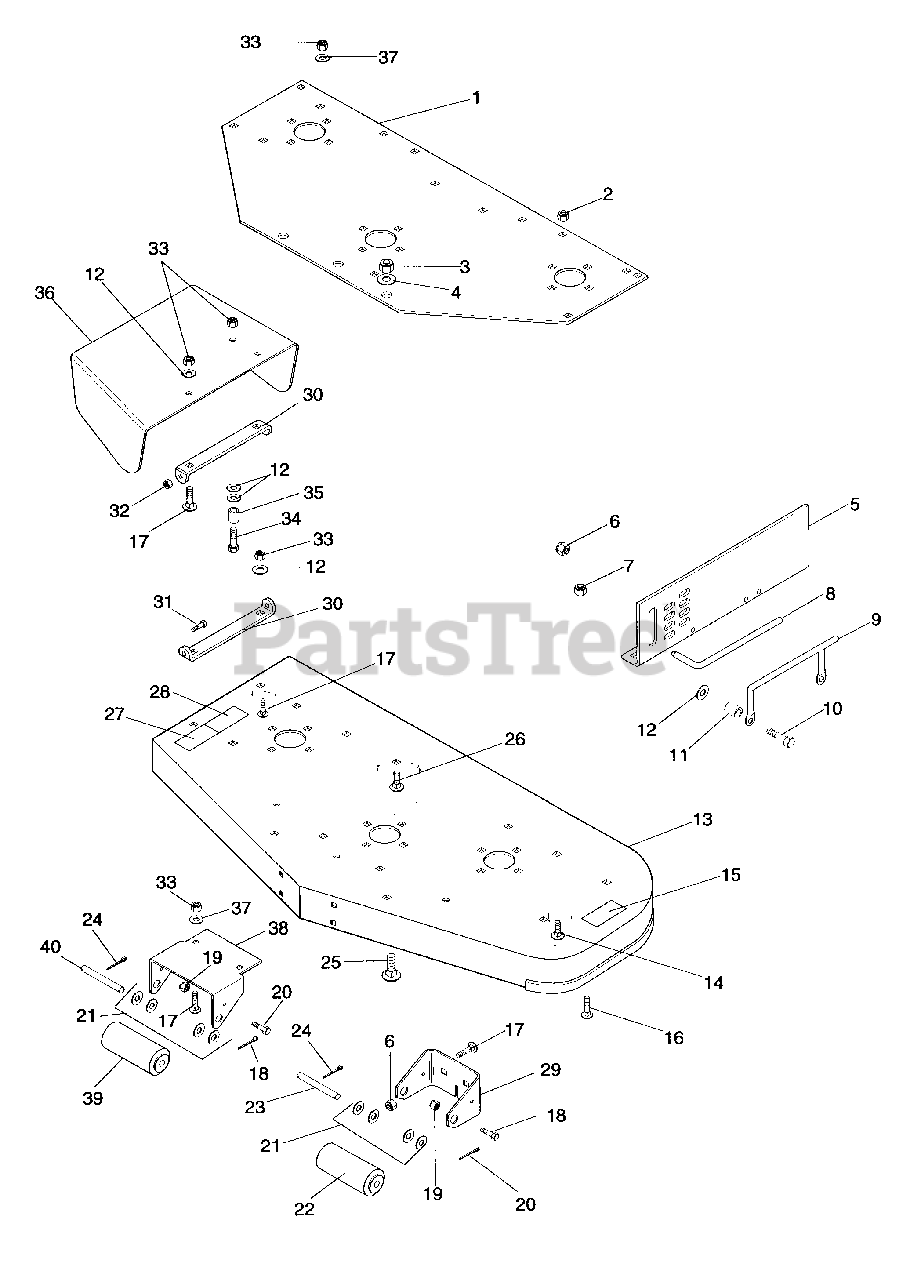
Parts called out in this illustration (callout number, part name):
1	Plt,Support
2	Nut - Lk - Nyl .312 - 18 Pl
3	Nut - Lk - Nyl .50 - 13 Pl
4	Wshr - FL - Stl .531 x 1.250 x .100
5	Brkt, Mwr Side Sprt L.N.
5	Brkt, Mwr Side Sprt R.H.
6	Nut - Lk - Nyl.375-16 PL
7	Nut - Lk - Nyl .312 - 18 PL
8	Pin, Mower Locking
9	Handle
10	Blt - Hex .38 - 16 x 1.75 Pl Gr 5
11	Bushing
12	Wshr - Fl - Stl .406 x .812 x .065 Pl
13	Wldmt, 50" Mwr Fabricated
14	Blt, 5/16 - 18 x .625 Rdhdsqnk
15	Decal, Danger Foot
16	Blt, Carriage 5/16 - 18 x 1.0
17	Blt - Rdhdsqnk .38 - 16 x 1.0 Pl
18	Blt - Hex .25-20 x.75 Pl Gr 5
19	Nut - Lk Nyl .250 - 20 Pl
20	Pin - Cotr .250 x 2.00
21	Wshr - Fl - Stl .656 x 1.312 x .095 Pl
22	Rlr, Gage
23	Rod
24	Pin - Cotr .25 x 1.00
25	Bit - Rdhdsqnk .50 - 13 x 1.00
26	Blt, Carriage 3/8 - 16 x .75
27	Decal, Warning Eye
28	Decal, Danger Hand
29	Brkt, Roller
30	Brkt, Chute
31	Blt - Hex .25 - 20 x .875
32	Nut - Lk - Nyl .250 - 20 Pl
33	Nut - Lk - Nyl .375 - 16 Pl
34	Blt - Hex .38 - 16 x 1.50 Pl Gr 5
35	Bshg - Slv .407 x .625 x .750 Pl
36	Shield, Sfty Ext 50" Mwr
37	Wshr - Fl - Stl .406 x .812 x .065
38	Brkt, Gage Roller
39	Rlr, Gage
40	Shft, Center Roller
